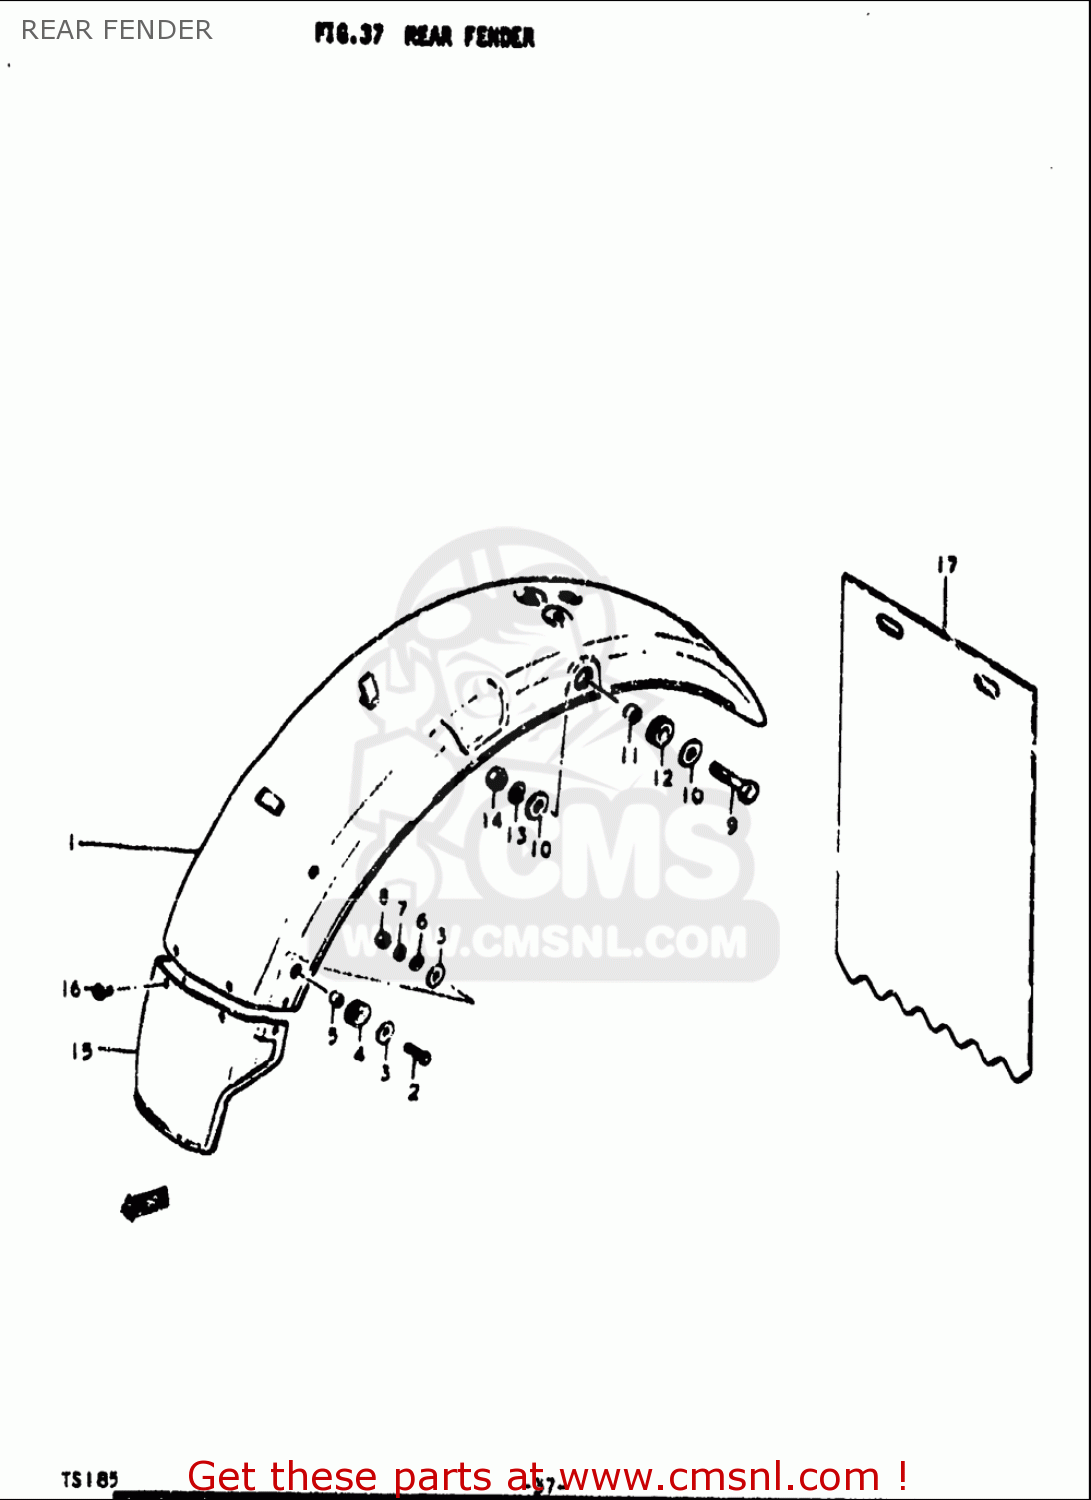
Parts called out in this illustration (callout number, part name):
2	BOLT
3	WASHER(6.5X20X1.2)
4	CUSHION
6	WASHER
7	WASHER,LOCK
8	NUT
9	BOLT
10	WASHER(10.5X24X1.6)
11	SPACER
12	CUSHION
13	WASHER,LOCK
14	NUT
16	SCREW
